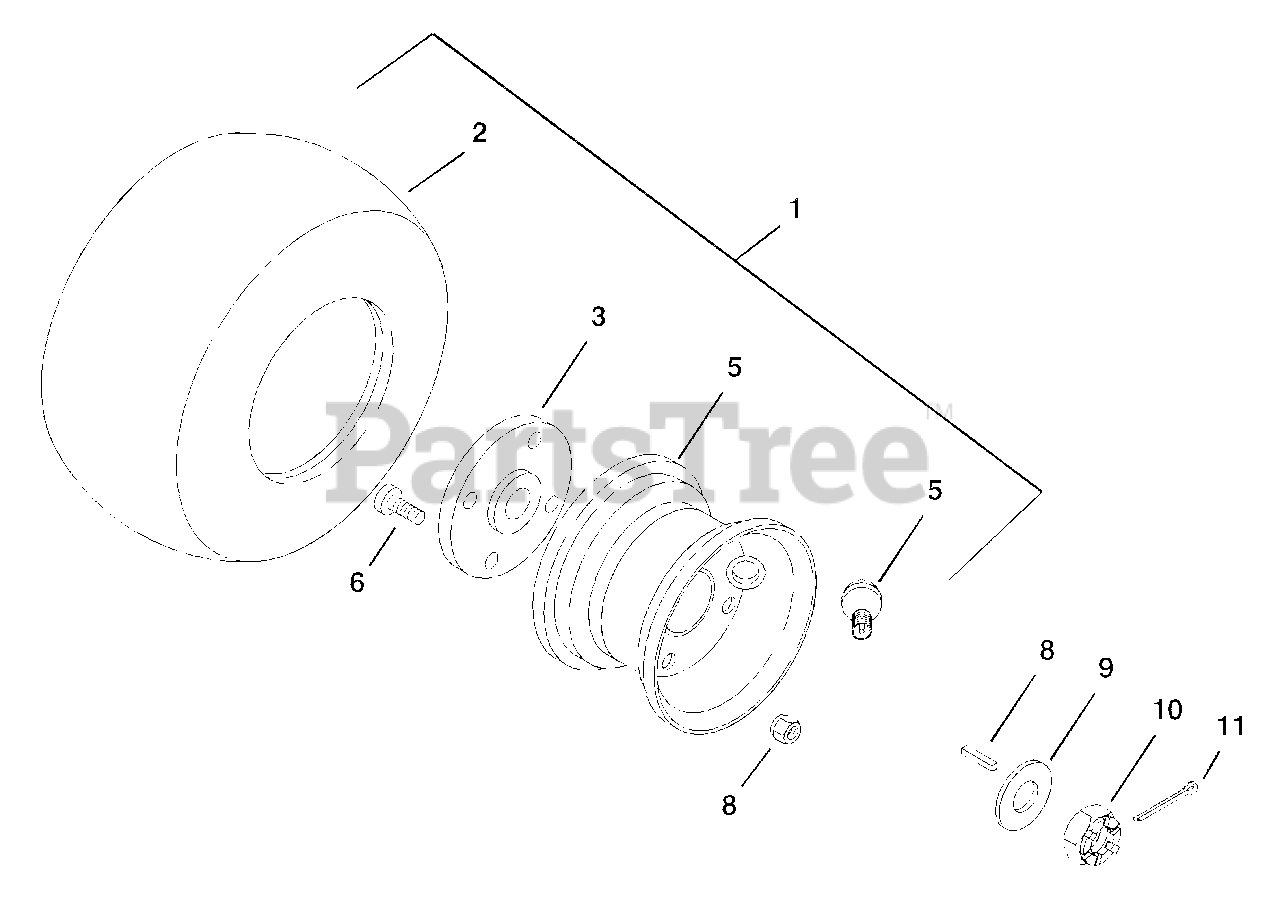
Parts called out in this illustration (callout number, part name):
1	T/WHL ASSY 16X6.50-8
2	TIRE 16X6.50-8
3	ASM,HUB
5	VALVE STEM ASS'Y
6	LUG BOLT, .5-20 X 1.25
7	NUT-LUG .50-20 YWZC
8	KEY-SQ .188X.75X.188
9	WSHR-FL-STL.755X1.375X.062YWZC
10	NUT,HEX 3/4-28 SLOTTED
11	@PIN-CTR .09X1.00 EXTPRSQCT YZ
